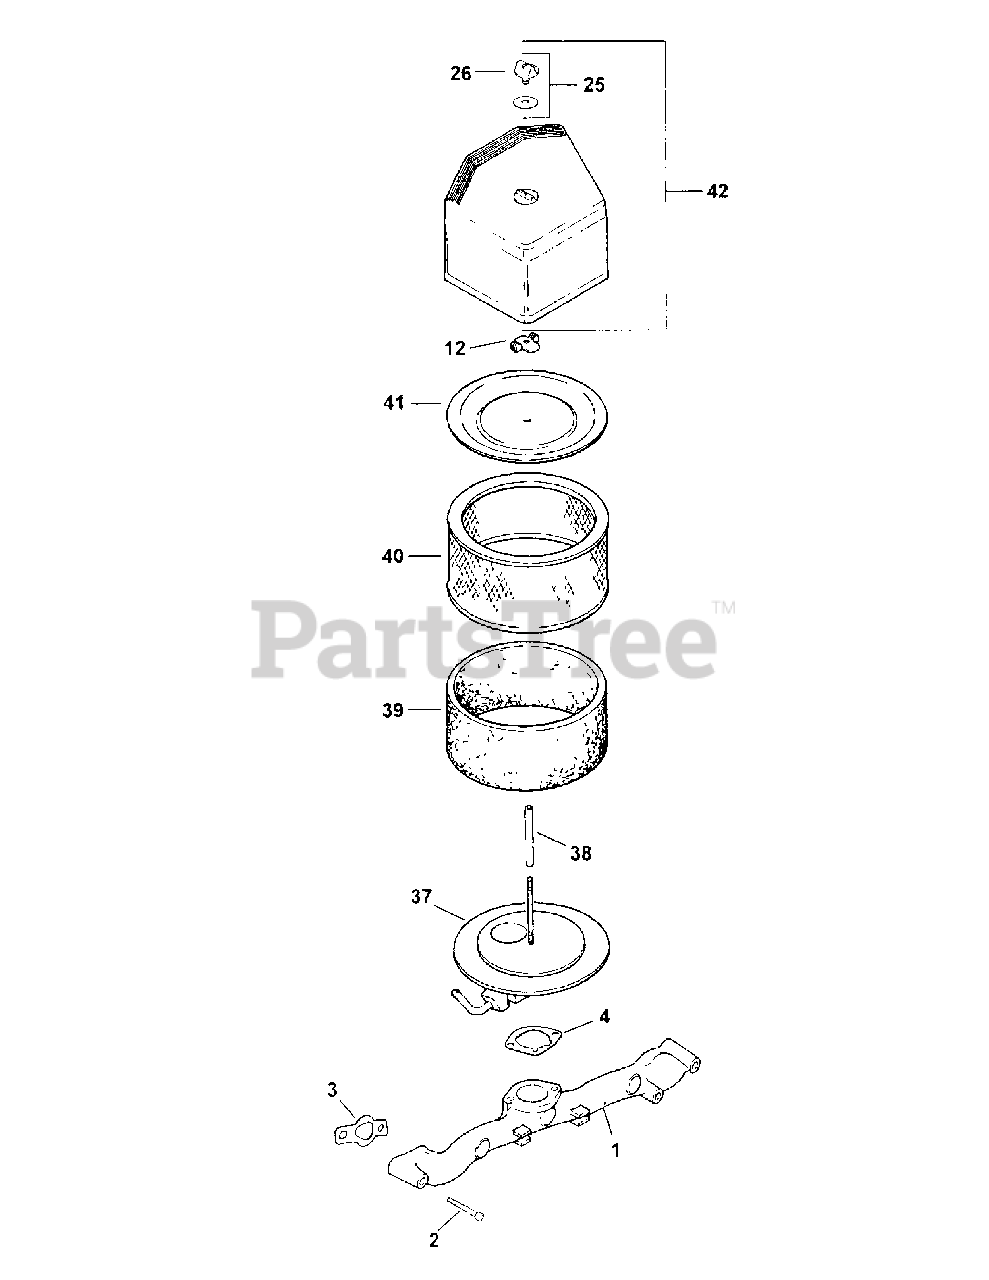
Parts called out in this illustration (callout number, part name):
1	Manifold, Intake
2	Screw, Hex Flange
3	Gasket, Intake Manifold
4	Gasket, Air Cleaner Base
12	Nut, Wing
25	Kit, Air Cleaner Knob w/Gasket
25	Gasket, Air Cleaner Knob Cover
26	Knob, Air Cleaner Cover
37	Elbow, Air Cleaner
39	Element, Precleaner
40	Elements, Air Cleaner & Precleaner
41	Cover, Air Cleaner Element
42	Kit, Air Cleaner Cover
